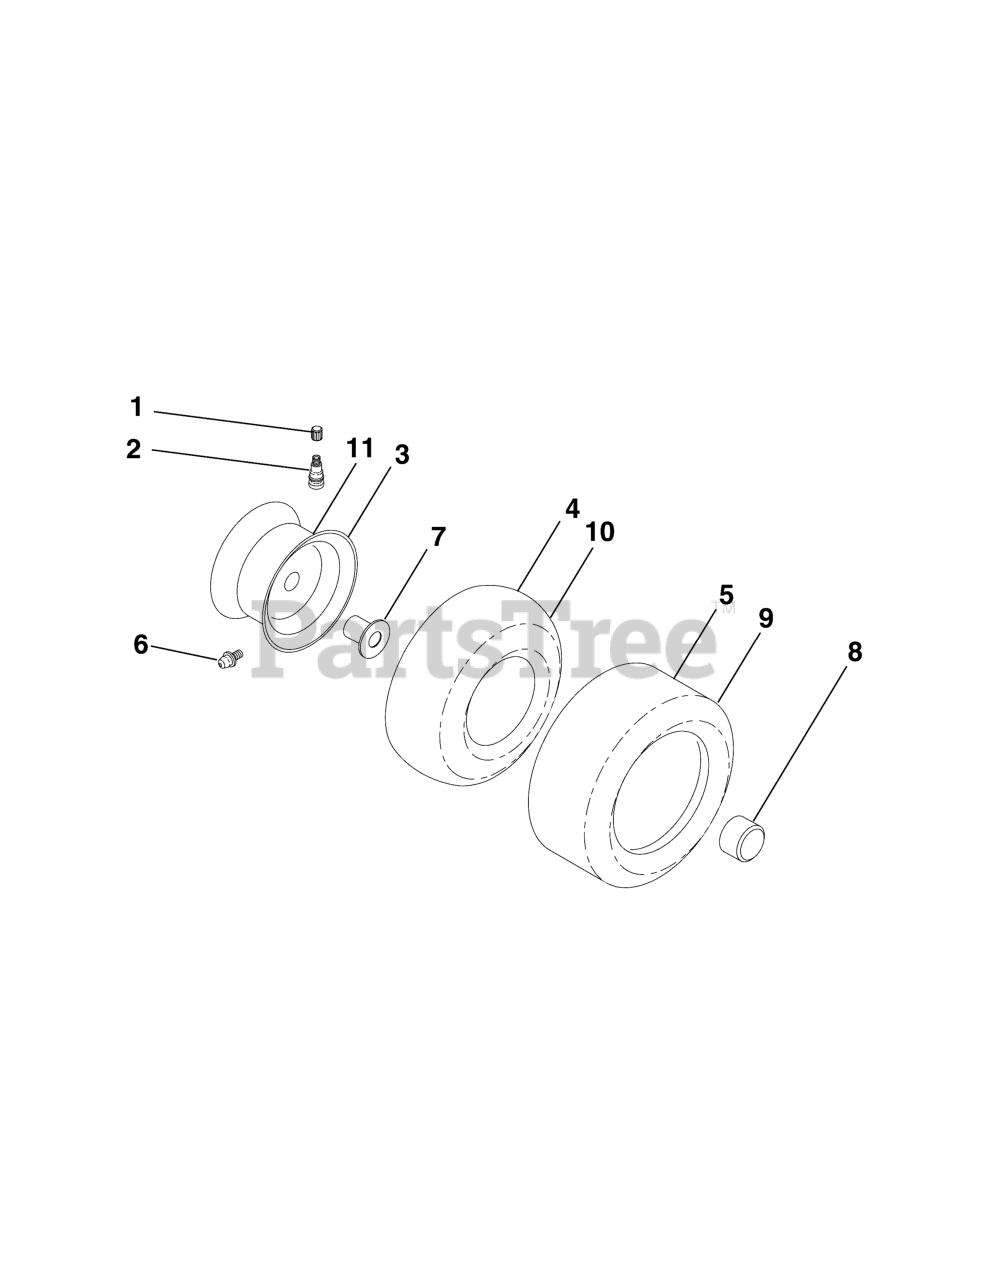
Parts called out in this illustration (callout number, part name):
1	Cap, Valve, Tire
2	Stem, Valve
3	Rim Assembly, Front
4	Tube, Front
5	Tire, Front
6	Fitting, Grease
7	Bearing, Flange
8	Cap, Axle (Front Wheel Only)
9	Tire, Rear
10	Tube, Rear
11	Rim Assembly, Rear
